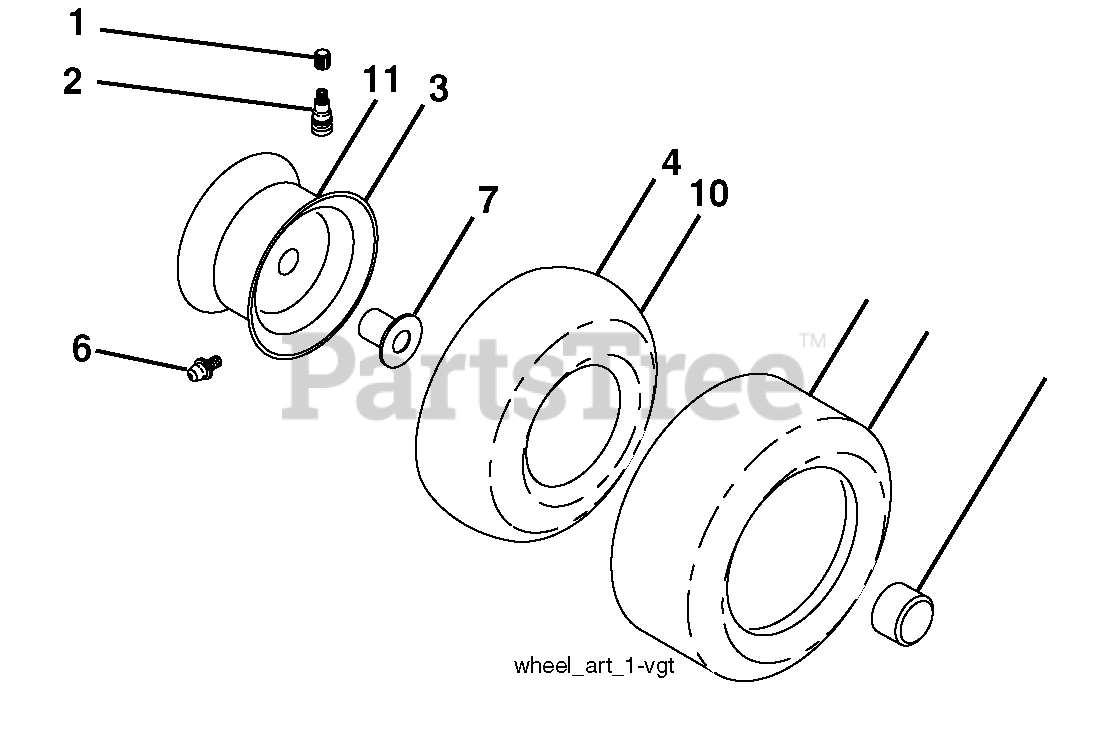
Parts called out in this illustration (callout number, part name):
1	Cap, Valve, Tire
2	Stem, Valve
3	Rim Assembly, Front
4	Tube, Front
5	Tire, Front
6	Fitting, Grease
7	Bearing, Flange
8	Cap, Axle
9	Tire, Rear
10	Tube, Rear
11	Rim Assembly, Rear
11	Sealant, Tire (10 oz. Tube)
